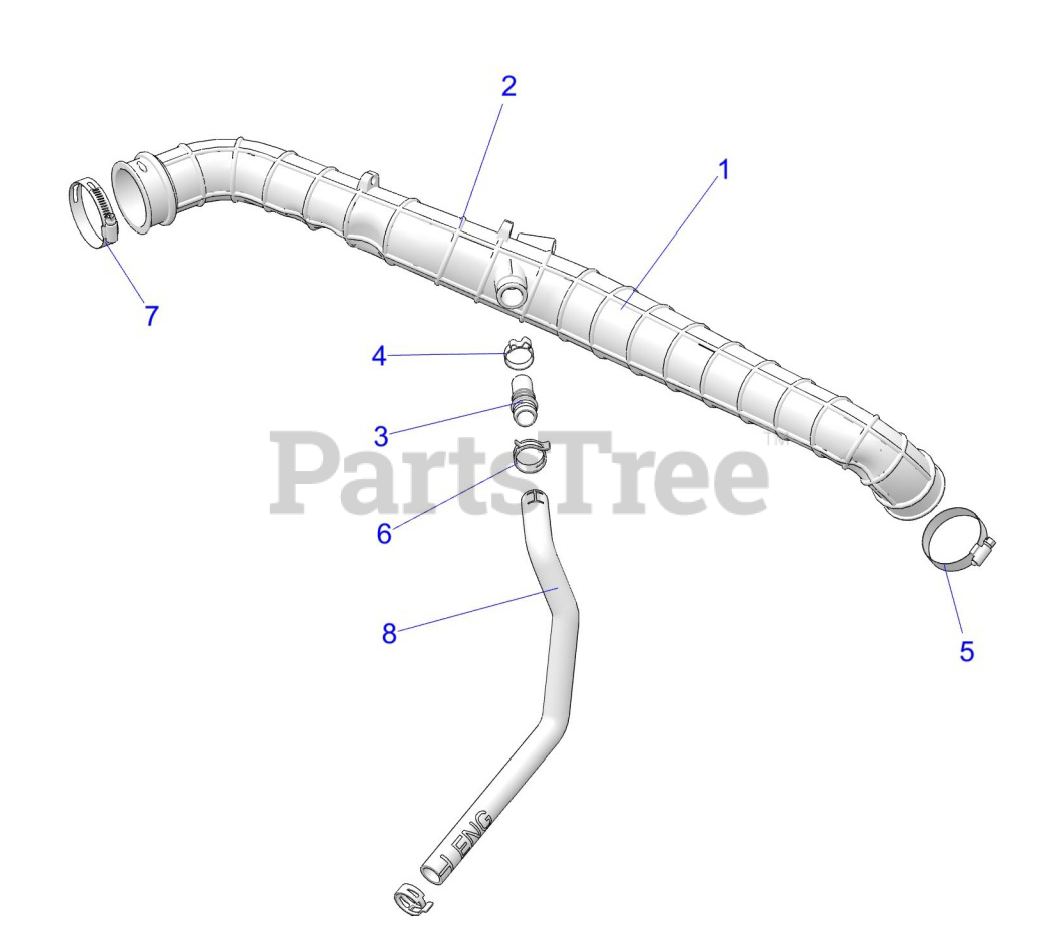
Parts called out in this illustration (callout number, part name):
1	ASM-INTAKE,POST-FILTER
2	HOSE-INTAKE,POST-FILTER
3	FITTING-3/4 DOUBLE BARB
4	CLAMP-HOSE
5	CLAMP, HOSE, S.S.(10)
6	SPRINGBAND-CLAMP 27/12,GREEN
7	CLAMP-HOSE SLOTTED,60-80 DIA
8	HOSE-VENT,ENGINE
